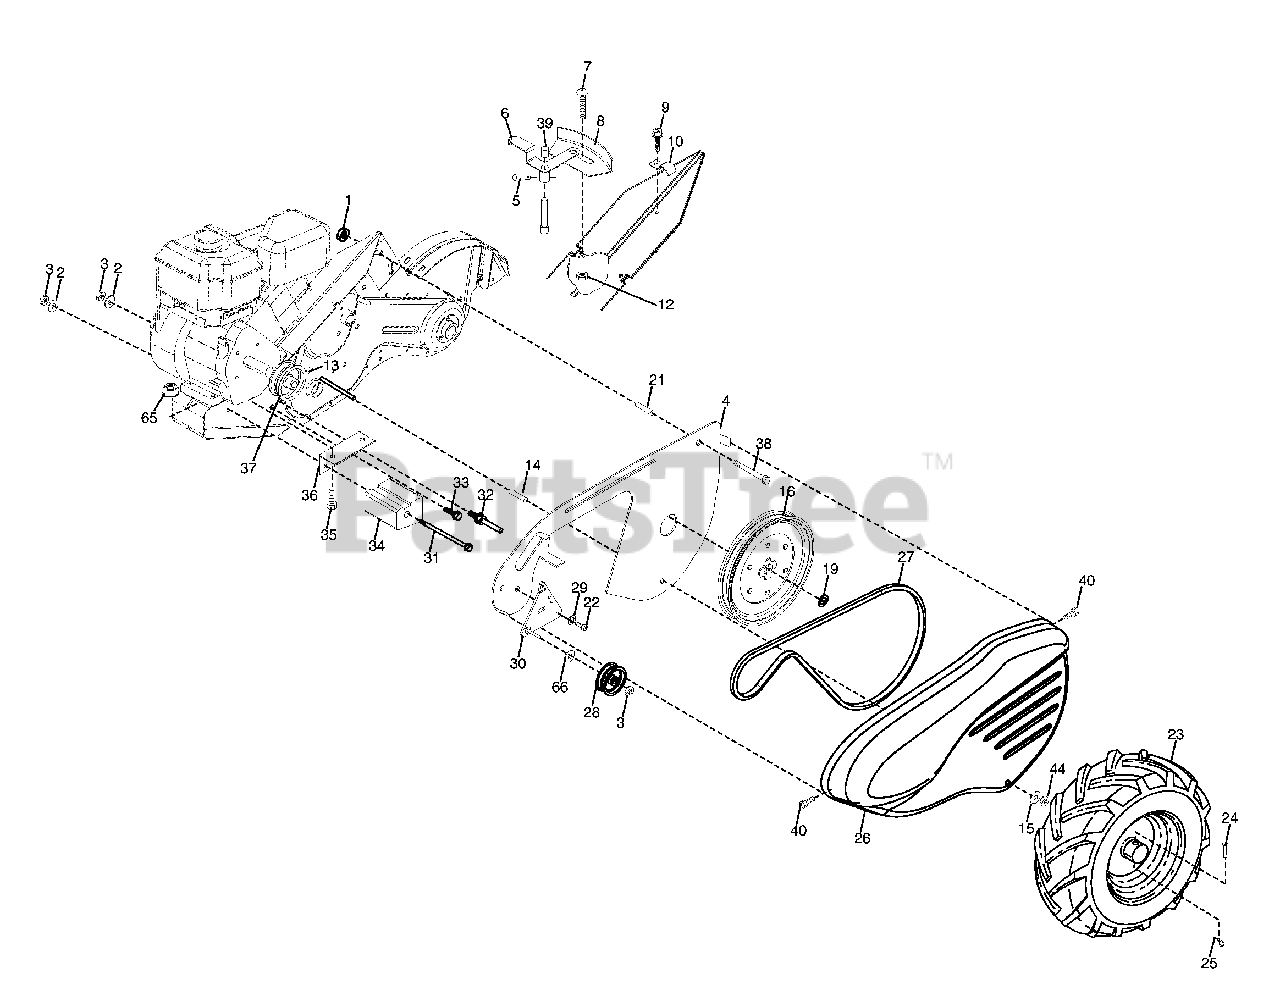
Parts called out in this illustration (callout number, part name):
1	Nut, Keps 5/16-18
2	Washer, Lock 3/8
3	Nut, Hex 3/8-16
4	Shield, Inner Belt Guard
5	Pin Spirol Flared
6	Lever, Shift
7	Bolt, Carriage 1/4-20 x 1/2 Gr. 5
8	Plate, Shift Indicator
9	Screw, Hex, Washer Head, Slotted #10-24 x 1/2
10	Clip
12	Nut, Keps Hex 1/4-20 unc
13	Screw, Set, Hex 5/16-18 x 3/8
14	Spacer, Split 0.327 x 0.42 x 1.220
15	Washer 11/32 x 11/16 x 16 Ga.
16	Sheave, Transmission
19	Ring, Retainer
21	Spacer, Split 0.327 x 0.42 x 2.09
22	Bolt, Fin Hex 5/16-24 x 1/2
23	Tire
24	Rivet, Drilled
25	Clip, Hairpin
27	Belt, V
28	Pulley, Idler
29	Ring, Klip
30	Bracket, Idler
31	Bolt, Hex 5/16-16 x 12
32	Shaft, Idler Arm
33	Bolt, Hex 3/8-16 x 1
34	Counterweight, L. H.
35	Bolt, Hex 5/16-18 x 1-1/2
36	Bracket, Reinforcement, L. H.
37	Sheave, Engine
38	Bolt, Fin Hex 5/16-18 x 2-3/4
39	Cap, Plunger
40	Screw Hex Wsh Slt # 10-24 x .50
44	Nut, Lock 5/16-18
65	Nut, Lock Hex Flange
66	Washer 13/32 x 13/16 x 12 Ga.
